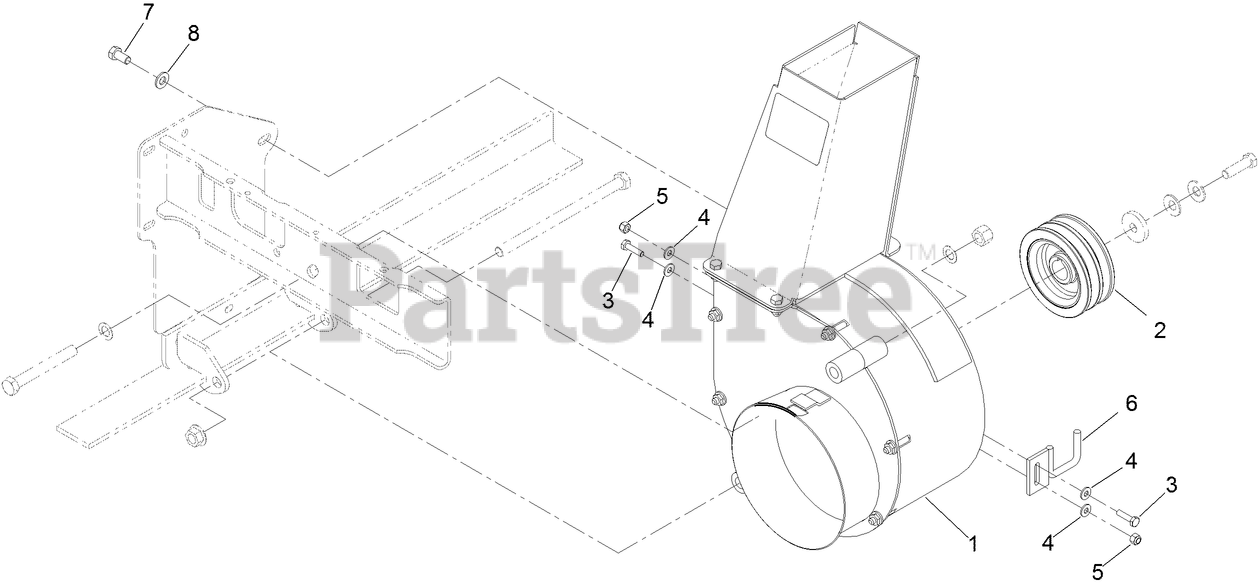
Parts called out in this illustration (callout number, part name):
1	BLOWER ASM
2	SHEAVE
3	SCREW-HH
4	WASHER-FLAT
5	NUT-LOCK, NI
7	SCREW-HH
8	WASHER-FLAT
